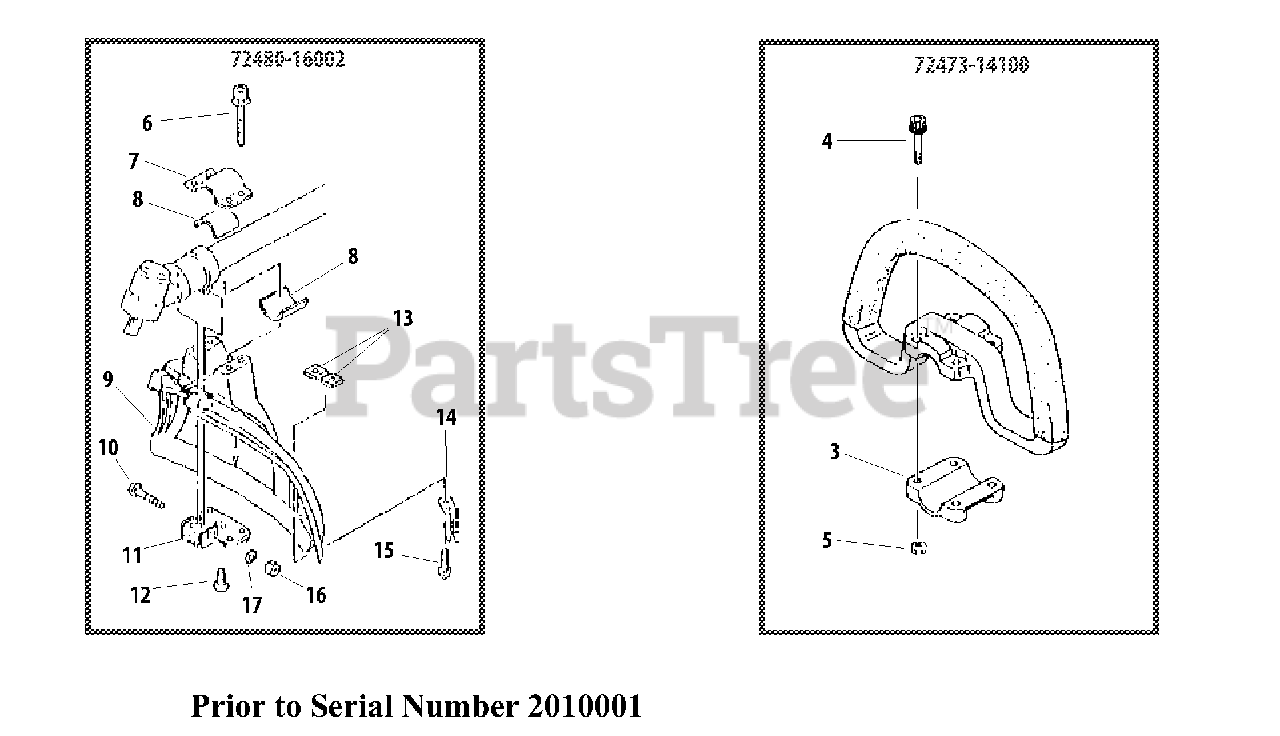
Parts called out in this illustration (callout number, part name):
3	CAP - LOWER
4	SCREW - 5X30
6	SCREW - 5X45
7	CLAMP - UPPER
8	SPACER
9	SHIELD, DEBRIS - BLACK
10	SCREW - 5X35
11	CLAMP - LOWER
12	SCREW
13	NUT - 5
14	KNIFE, TRIMMER LINE
15	SCREW - 5X16
17	WASHER - 5
72473-14100	HANDLE ASSY
72480-16002	DEBRIS SHIELD KIT
